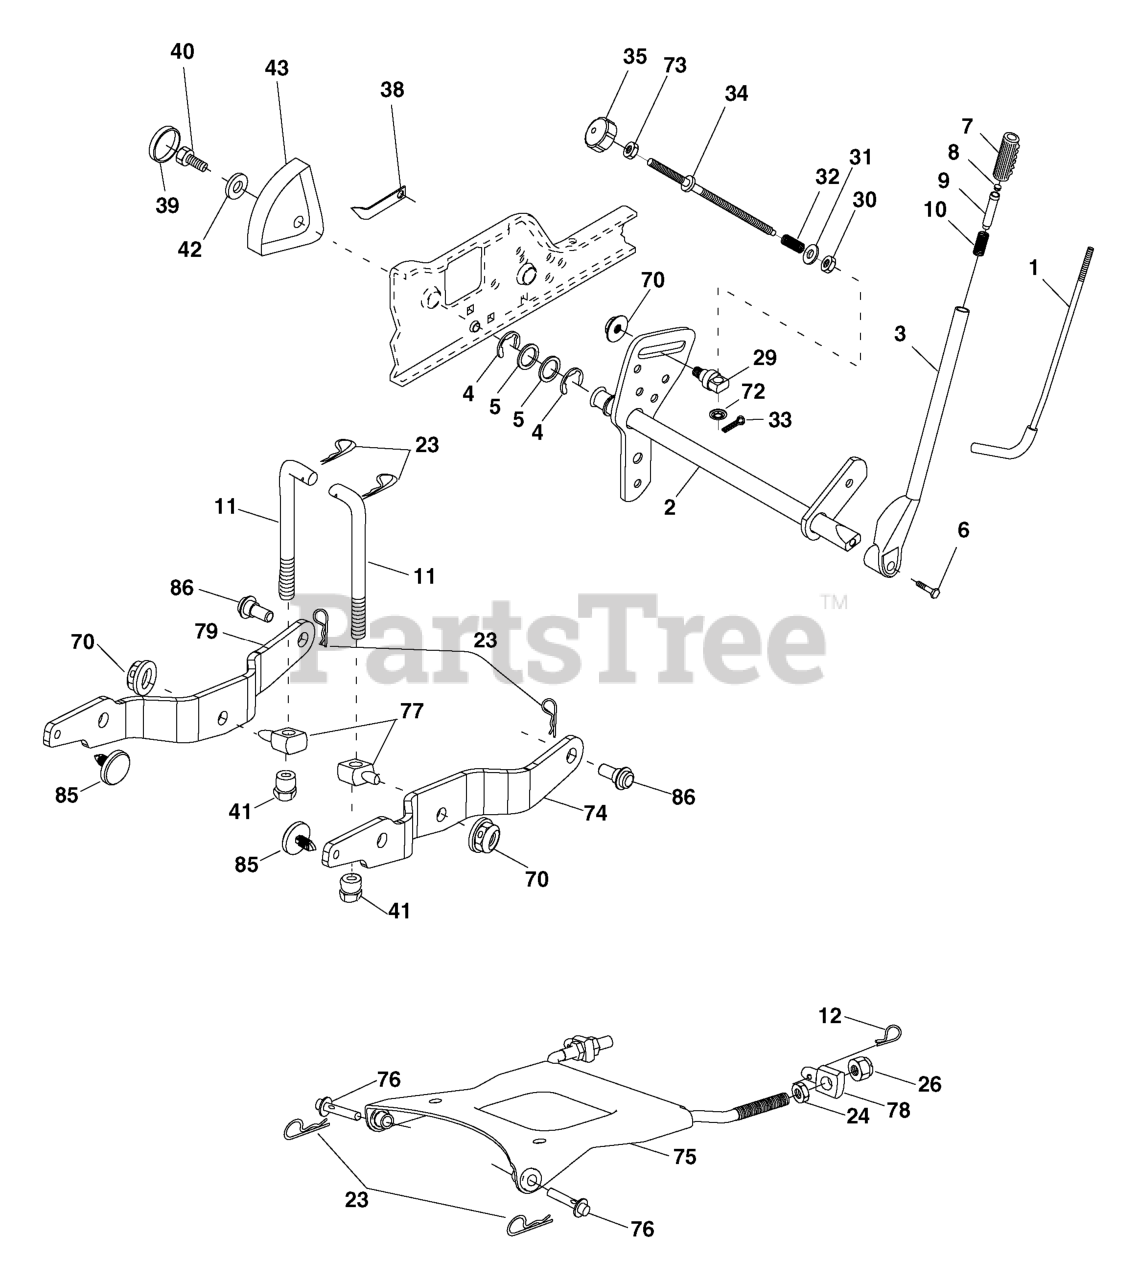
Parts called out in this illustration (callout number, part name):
1	LEVER ROD LT
2	SHAFT ASM., LIFT VGT
3	LEVER ASSY-LIFT RH
5	Washer 29/32 x 1-1/4 x 16 Ga.
6	Bolt, Fin Hex 3/8-16 x 1-1/2
7	GRIP HANDLE
8	PLUNGER BUT KIT
9	PLUNGER BUT KIT
10	SPRING 0.620D X 2.125
11	LIFT LINK
12	SPRING RETAINER
23	RETAINER-SPRNG RB
24	NUT.HEX.JAM.1/2-13
26	NUT.LK.W/WSH.1/2.
29	Trunnion Infin Height
32	SPRING.COMP.INF.H
33	COTTER PIN
34	ROD.LIFT.ADJUSTABLE
35	KNOB INF 3/8-16
38	POINTER, HEIGHT INDICATOR(2 2)
40	SCREW 5/16-18X1
41	NUT, LIFT LINK 7/16-20
43	HEIGHT INDICATOR
70	NUT
72	NUT PUSH M
73	NUT
74	ARM.SUSP.REAR.RH
75	PLATE ASM SUSP FRONT
76	PIN.FLANGE
79	ARM SUSPENSION LH
85	INSERT WEAR (3 2)
86	BOLT.SHOULDER
